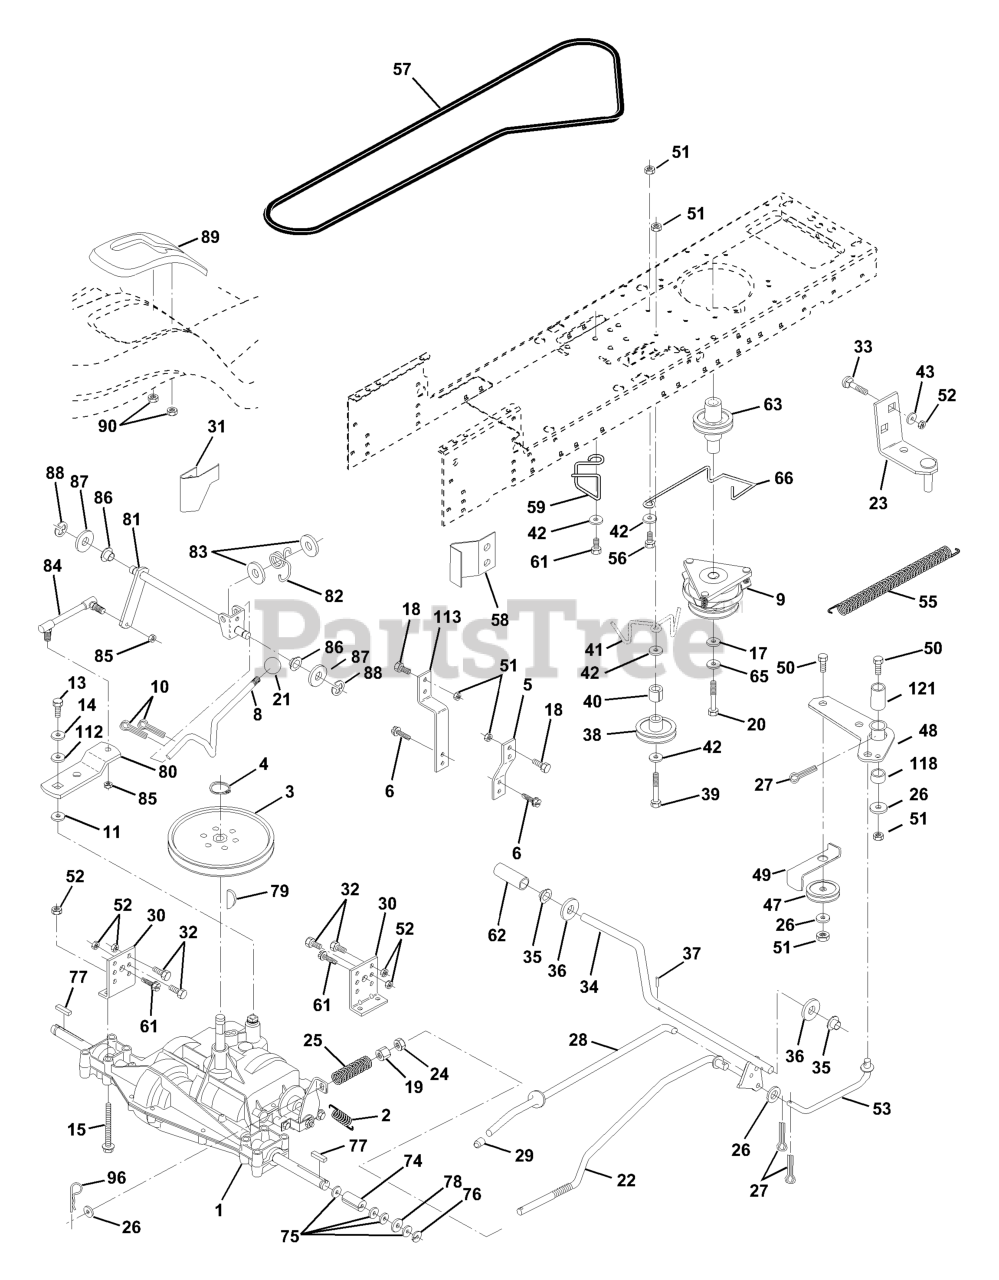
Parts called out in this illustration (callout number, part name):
2	SPRING,BRAKE RETURN
3	PULLEY TRANS
4	RETAINING RING LT
5	STRAP TORQUE
6	SCREW.THDROL.5/16-18X3/4.TTY
8	ROD SHIFT FENDER
9	CLUTCH.ELECT.CVX.105 FT/LB.
10	PIN COTTER
11	WASH-SHFT PLT LT
13	BOLT 1/4-28X3/4
14	LOCKWASHER
15	BOLT HEX 5/16-18 GR 5
18	BOLT
19	NUT
20	BOLT HEX
21	KNOB.DUCKHEAD.1/2
23	BRACKET ASM MTG
24	NUT
25	SPRING ROD LT
26	WASHER
27	COTTER PIN
28	ROD BRAKE PARK LT
29	PLUNGER CAP
30	BRACKET TRANSAXLE
31	KEEPER BELT LH
32	BOLT
33	RP BOLT 5/16-18 X3/4 ZN/YEL GR
34	SHAFT, FOOT PEDAL
35	BEARING.NYLON
36	WASHER LT
37	DRIVE PIN
38	PULLEY.IDLER.FLAT
41	KEEPER, BELT IDLER
42	WASHER
43	WASHER T
47	IDLER PULLEY
48	BELLCRANK ASSEMBLY
49	RETAIN BELT
50	BOLT
52	LOCKNUT
53	LINK, CLUTCH LT
55	SPRING, RETURN LT
57	V-BELT
59	KEEPER CENTER SPAN
61	SCREW
62	COVER, PEDAL (1 2)
63	PULLEY CLU ELEC
65	LOCKWASHER
66	KEEPER BELT ENGINE
74	SPACER AXLE
77	SQUARE KEY
79	KEY STD (1373) DANA
81	SHAFT ASM CROSS 20"
82	SPRING,TORSION
83	WASHER
84	ROD TIE 20"
85	NUT LOCK CENTER 1/4 -28 FNTHD
86	BUSHING.STEERING.ROD LTB-WSL
89	CONSOLE SHIFT
90	NUT.PUSH.3/16
96	RETAINER M
112	WASHER LT
113	STRAP TORQUE LH LT
118	SPACER BELLCRANK
121	NYLINER CLUTCHING
